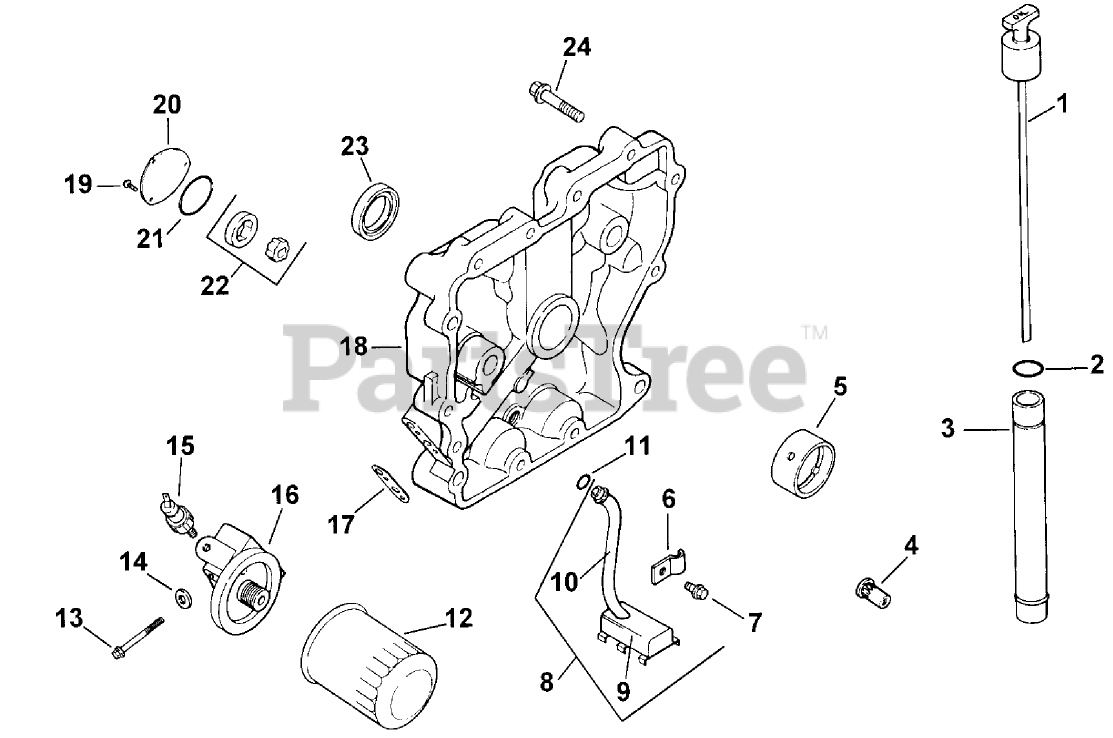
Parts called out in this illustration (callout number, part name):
1	Dipstick
2	O-Ring
3	Tube, oil fill
4	Valve-Oil Pressure
5	Bearing, crankshaft
6	Clip
7	Screw M5x0.8x16 (Only On: 72042, 72063, 72062, 72043)
8	Kit, oil pick-up (Includes 9, 10)
9	Pick-up, oil screen
10	Tubing, oil pick-up
11	O-Ring, oil pick-up
12	Filter-Oil
13	Screw, hex. flange M6x1.0x60
14	Washer
15	Swutch, oil pressure
16	Adapter, oil filter
17	Gasket, oil filter adapter
18	Plate, closure Asm (Includes 4,5,19-22)
19	Screw M5x0.8x16 (Only On: 72042, 72063, 72062, 72043)
20	Cover, oil pump
21	O-Ring, oil pump cover
22	Pump-Oil (Only On: 72042, 72063, 72062, 72043)
23	Seal-Crankshaft (Only On: 72042, 72043, 72062, 72063)
24	Screw
24	Screw M8x1.25x45 (Only On: 72103, 72083)
